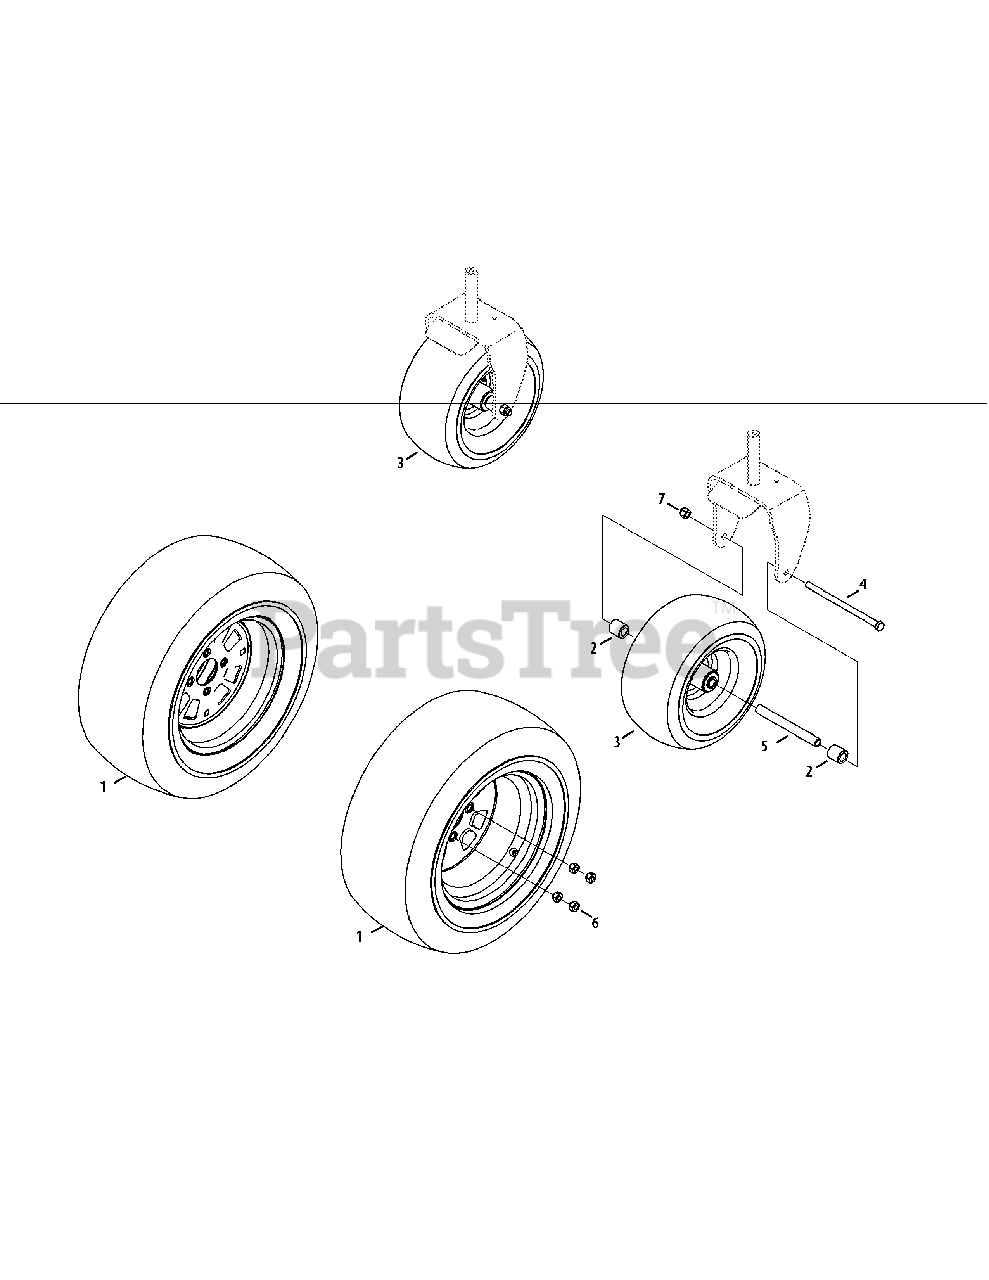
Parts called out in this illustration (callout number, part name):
1	Wheel Assy., Complete, 22 x 9.5 x 12
2	Hub, .76 x 1.23 x 1.25
3	Wheel Assy. Complete, 13 x 6.5-6
3	Ball Bearing
4	Hex Screw, 1/2-13 x 8.5
5	Spacer, .51 x .75 x 1.25
6	Lug Nut, 7/16-14
7	Hex Lock Nut, 1/2-13
